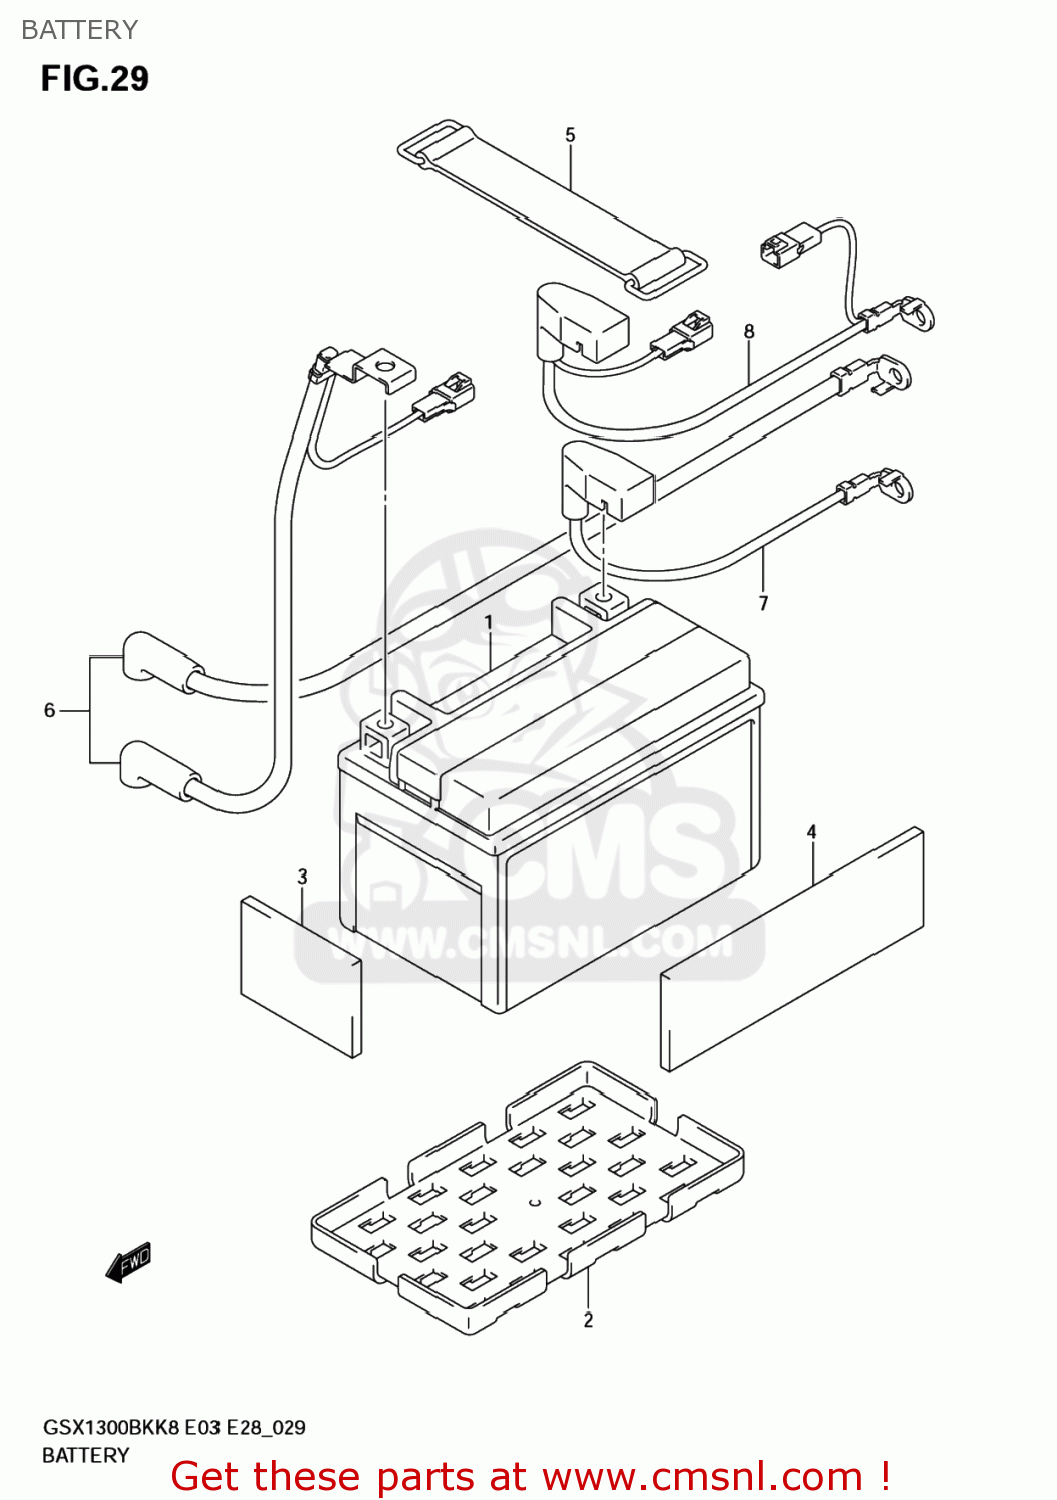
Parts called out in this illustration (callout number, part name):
1	BATTERY ASSY(YTX12-BS,12V10AH)
2	PROTECTOR,BATTERY
3	PROTECTOR(170X95X3.0)
4	PROTECTOR(170X95X3.0)
5	BAND
6	WIRE,STARTER MOTOR LEAD
7	WIRE,BATTERY PLUS LEAD
8	WIRE,BATTERY PLUS LEAD
